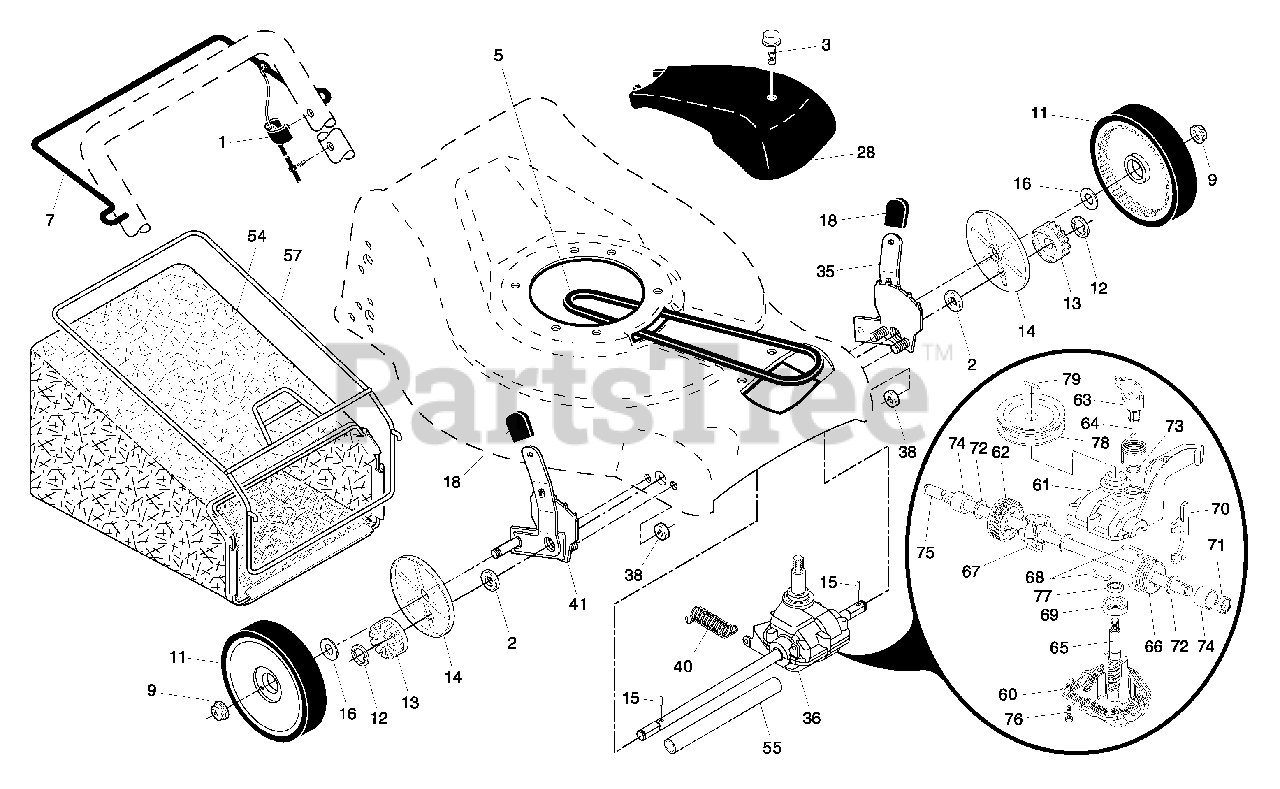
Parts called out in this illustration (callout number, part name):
1	Control Cable Assembly
2	Bearing, Wheel Adjuster
3	Pan Head Tapping Screw #10-24 x 2-3/4
5	V-Belt
6	Spring Retainer
7	Control Bar, Drive
9	Nut, Flangelock, Special Thread
11	Wheel & Tire Assembly
12	E-Ring
13	Pinion
14	Dust Cover
15	Pawl, Drive
16	Washer 1/2 x 1-1/2 x .134
18	Selector Knob
28	Dive Cover
35	Kit, Wheel Adjuster, LH
36	Gear Case Assembly, Complete
38	Locknut, Hex 1/4-20
40	Spring
41	Kit, Wheel Adjuster, RH
54	Grassbag
55	Driveshaft Cover
57	Frame, Grassbag
60	Case, Lower
61	Case, Upper
62	Gear, 27 Teeth
63	Lever, Clutch
64	Spring, Return
65	Shaft, Input
66	Dog, Movable
67	Dog, Fixed
68	Wire, Formed
69	Bearing, Ball
70	Fork, Shift
71	Seal, Output Shaft
72	Washer
73	Seal, Case
74	Bushing
75	Shaft, Output
76	Screw
77	Seal, Input Shaft
78	Drive Pulley
79	Pin, Retainer
